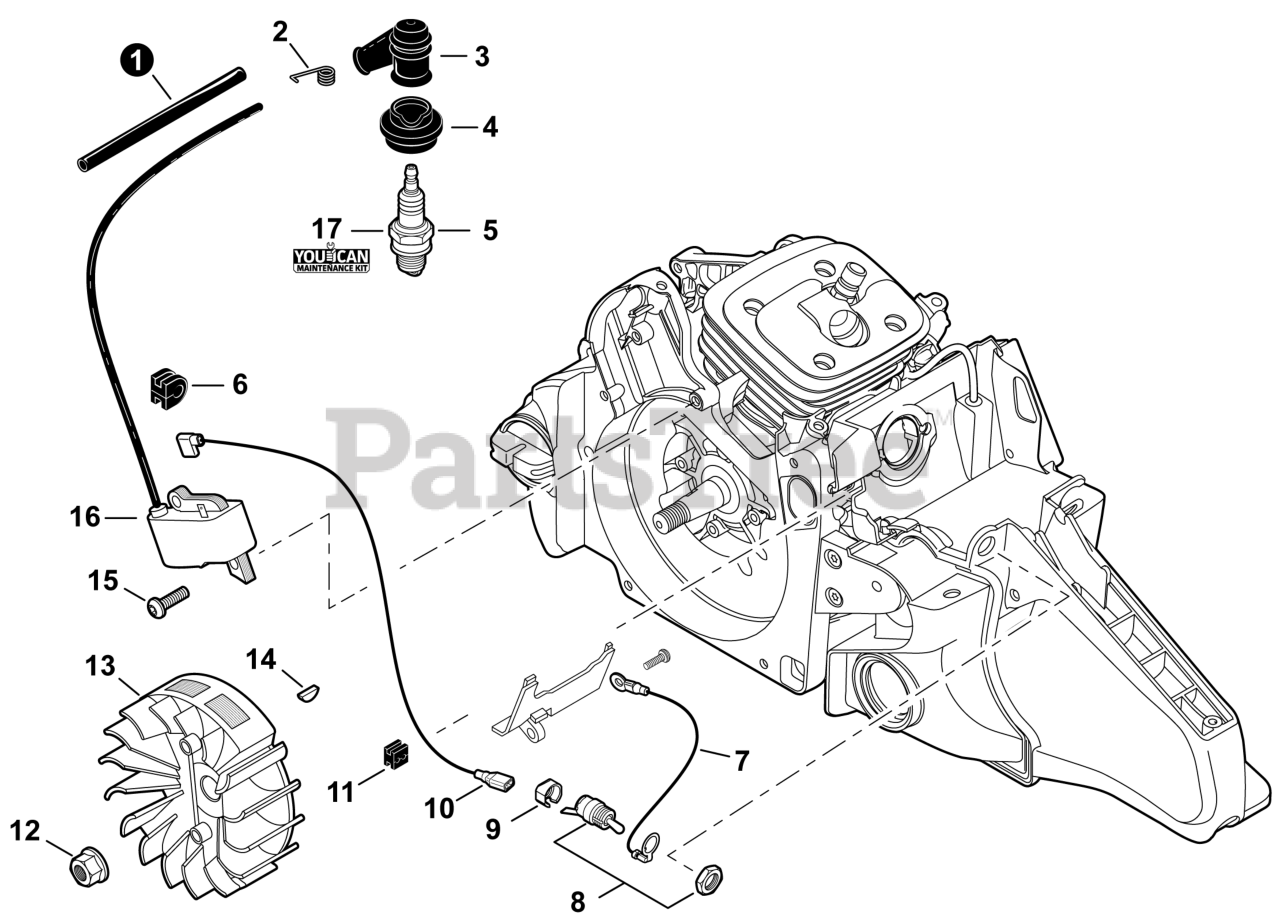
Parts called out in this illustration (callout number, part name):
1	TUBE, IGNITION COIL 6×7.2×70
2	TERMINAL, SPARK PLUG
3	CAP, SPARK PLUG
4	SEAL, SPARK PLUG
5	SPARK PLUG - BPMR8Y
7	LEAD - GROUND L= 170
8	SWITCH, ON-OFF
9	CAP, SWITCH
10	LEAD - IGNITION L= 280
11	GROMMET, LEAD
12	NUT, FLANGE M8
13	FLYWHEEL
14	KEY, WOODRUFF
15	BOLT, TORX 5×16
16	COIL, IGNITION
17	TUNE-UP KIT - YOUCANT
